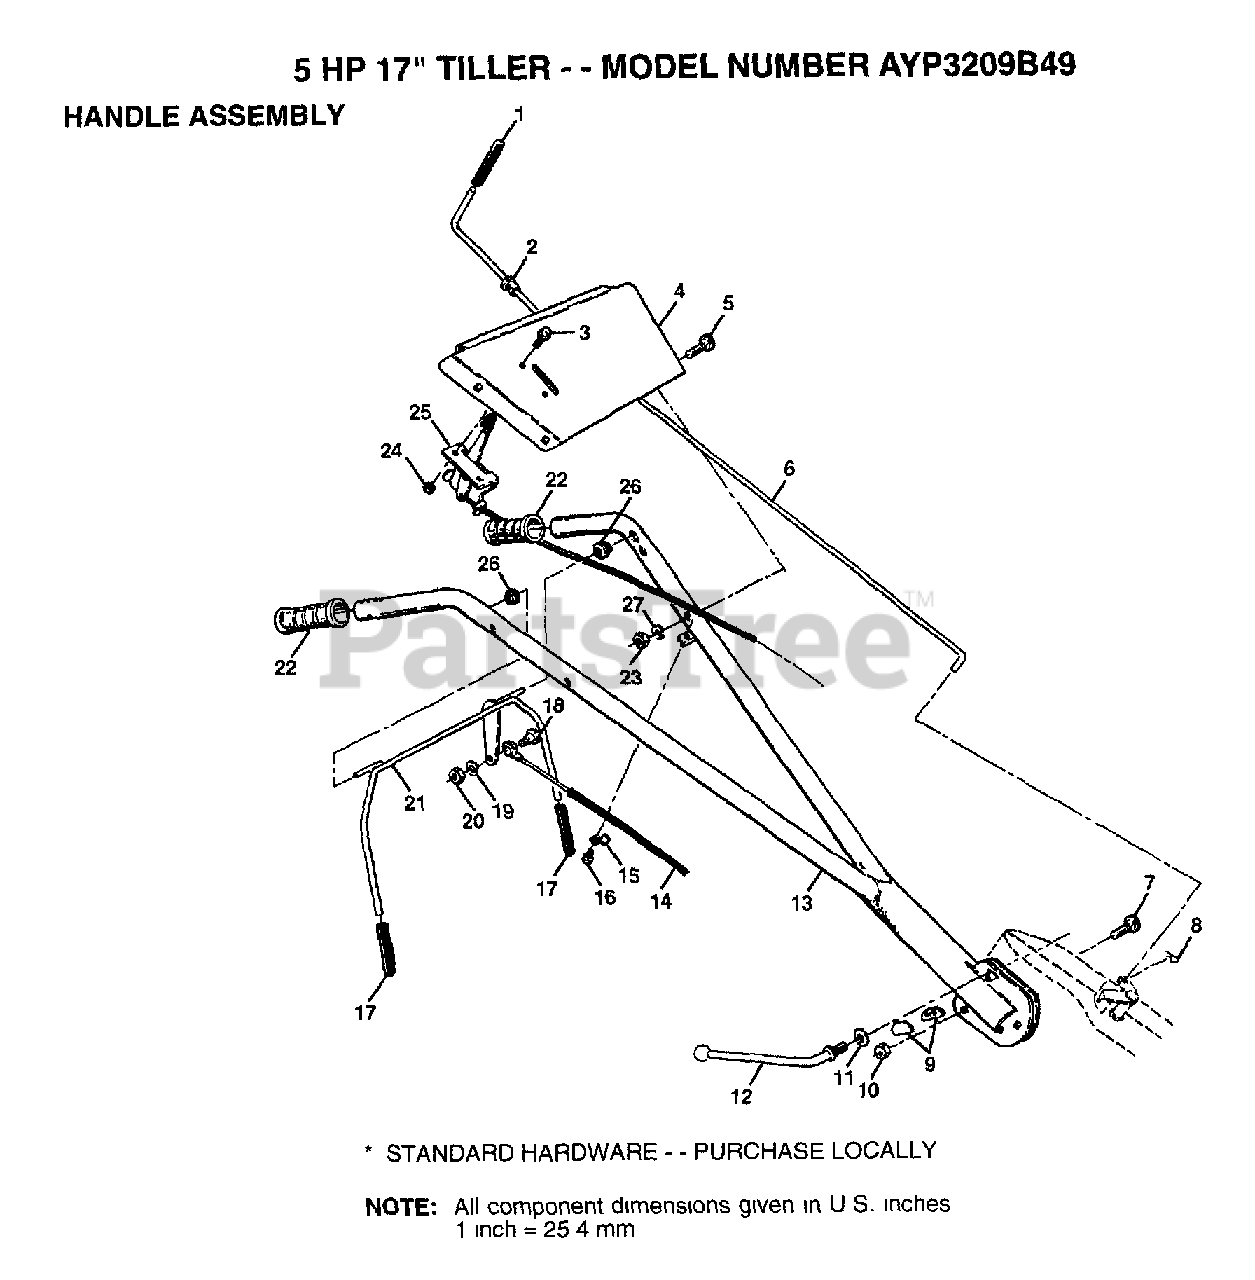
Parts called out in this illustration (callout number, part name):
1	GRIP TI
2	BUSHING
3	SCREW
4	HANDLE BRACKET
5	BOLT CARRIAGE CRT
6	ROD SHIFT CRT
7	BOLT D
8	RETAINER M
9	LOCK CRT
10	LOCKNUT
11	WASHER CRT
12	LEVER LOCK CRT
14	CABLE.CLUTCH.CRT
15	CONDIUT CLIP T
17	GRIP BAR CRT
18	SHOULDER BOLT ST
19	LOCKWASHER
21	HANDLE BAR CRT
22	GRIP HDLE NUBBED
23	NUT
25	"CONT,THROTTLE"
27	LOCKWASHER
